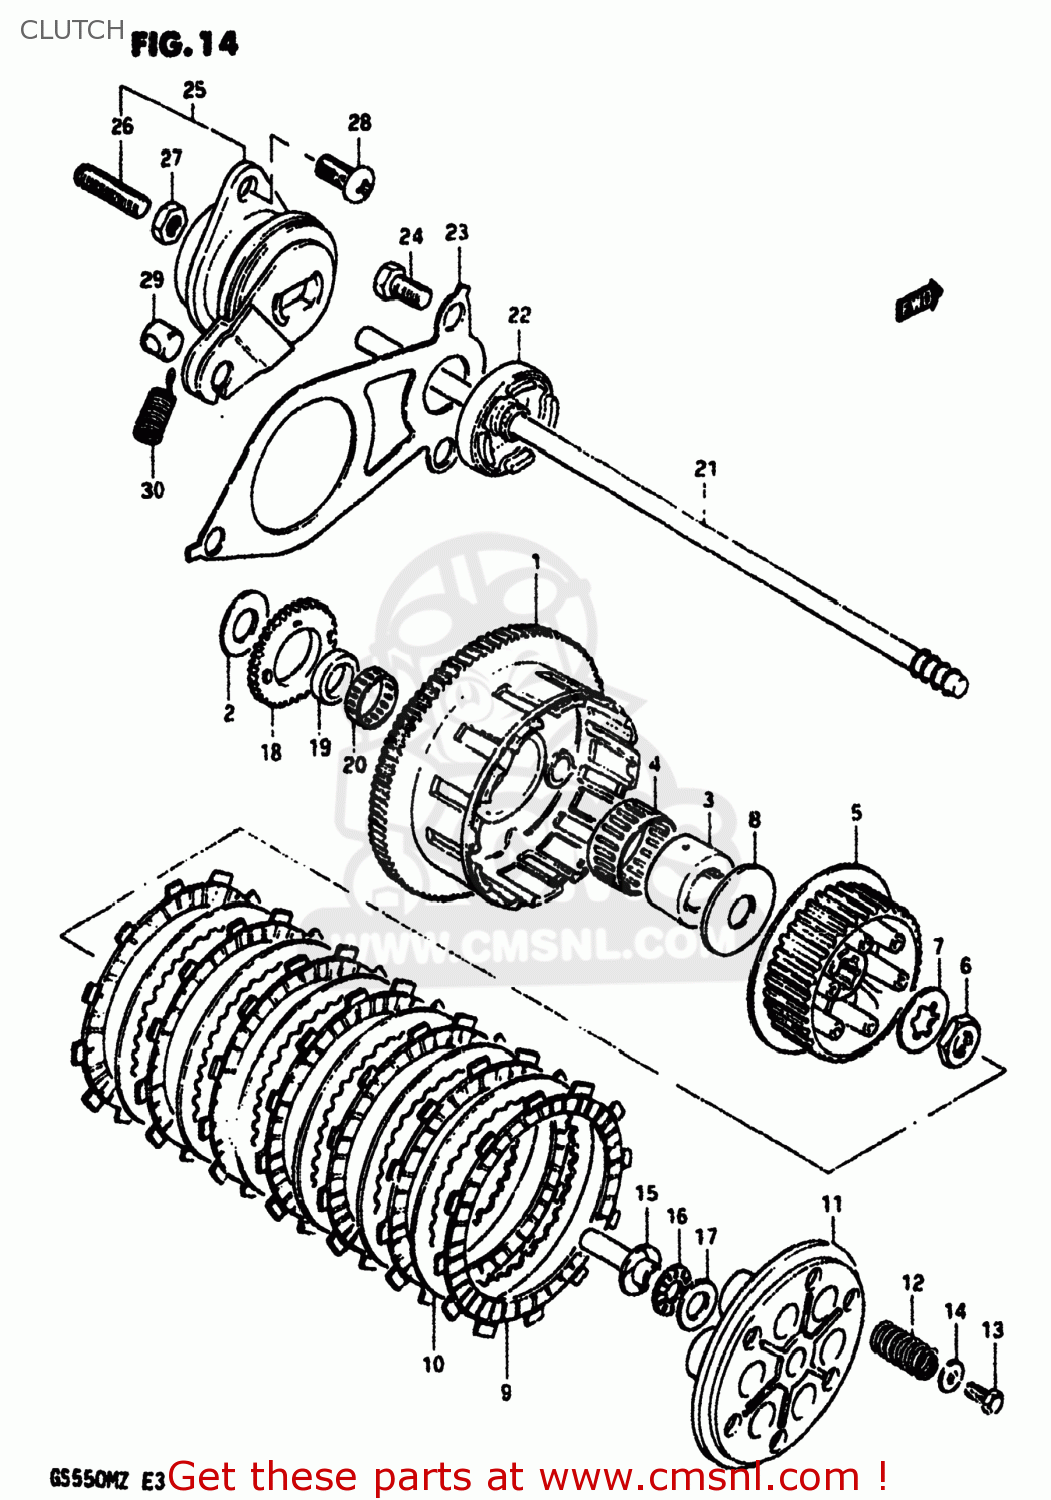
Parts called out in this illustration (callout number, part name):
1	GEAR ASSEMBLY,PRIMARY DRIVE NT:87
2	WASHER
3	SPACER,PRIMARY DRIVEN
4	BEARING
5	HUB,CLUTCH SLEEVE
6	NUT
7	WASHER,LOCK
8	WASHER(25X66X3.5)
9	PLATE,CLUTCH DRIVE (NAS)
10	PLATE,CLUTCH DRIVEN (NAS)
11	DISC,CLUTCH PRESSURE
12	SPRING
13	BOLT, UPPER
14	WASHER
15	PIECE,CLUTCH PUSH
16	BEARING(15X28X2)
17	WASHER
18	GEAR,ENG OIL PUMP DRIVE(NT:38)
19	SPACER,OIL PUMP DRIVE GEAR
20	BEARING(36X40X10)
21	ROD,CLUTCH PUSH
22	OIL SEAL
23	PLATE,CLUTCH PUSH ROD
24	BOLT
25	SCREW ASSY,CLUTCH RELEASE
26	SCREW
27	NUT 6MM
28	SCREW 6X12
29	PIECE,RELEASE ARM END
30	SPRING
